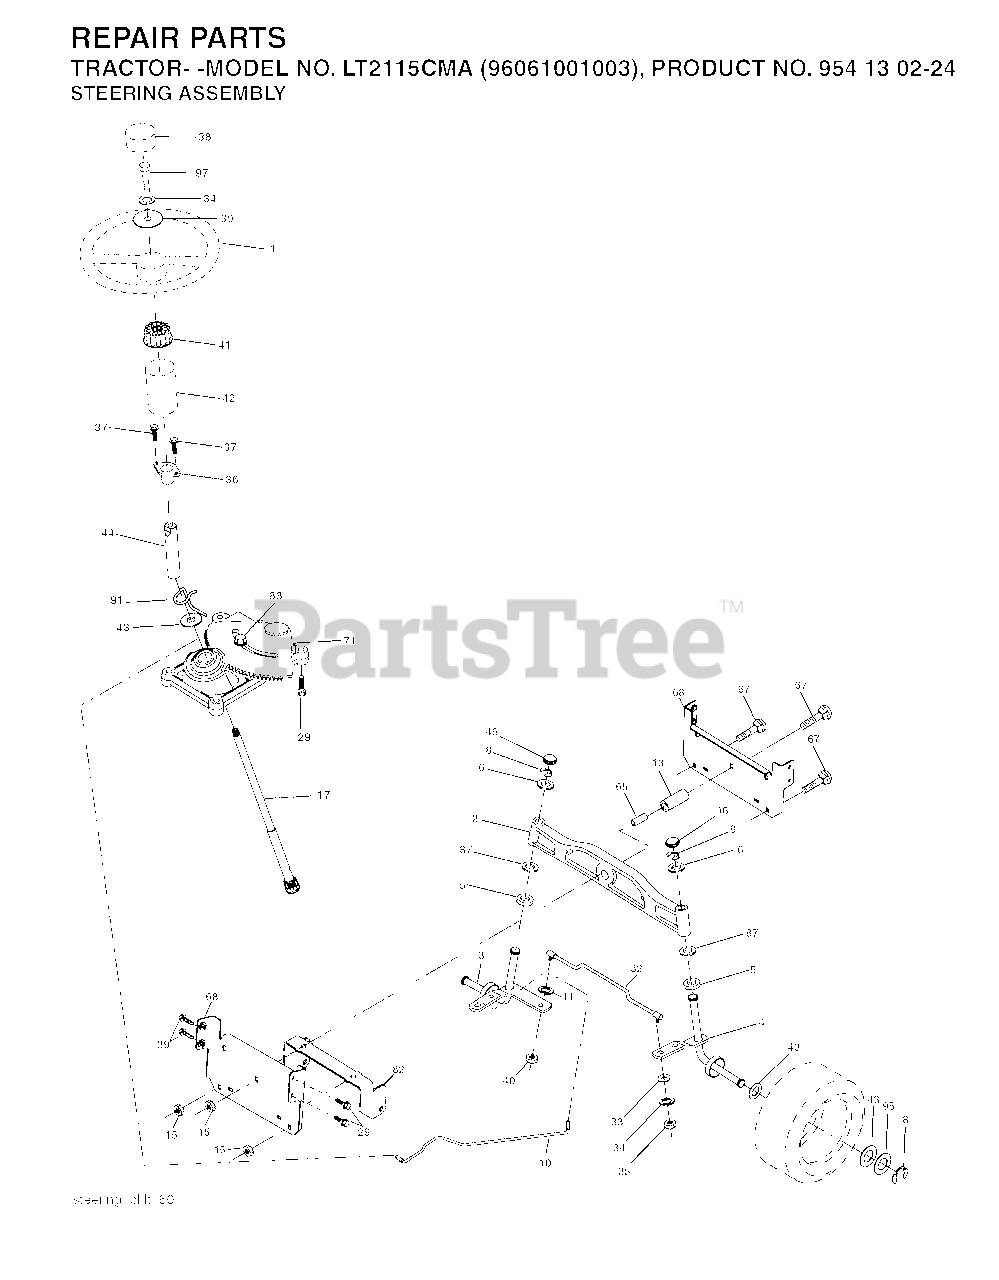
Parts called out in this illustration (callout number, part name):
1	WHEEL.STEERING.PREM.2.BLK
2	AXLE ASSY FRONT
3	SPINDLE.ASM.LH.15"TIRES
4	SPINDLE.ASM.RH.15"TIRES
8	RING CLIP
10	DRAGLINK.15".TIRES.2001
11	WASHER, LOCK 3/8
13	TUBE, PIVOT AXLE
15	NUT
17	SHAFT STEERING SPLINE
29	SCREW, 3/8-16X3/4
32	ROD.ASM.TIE.BALL.JOINT.NOVAN
33	WASHER M
34	LOCKWASHER
35	NUT, CROWNLOCK
36	BUSHING, STEERING
38	INSERT.CAP.STRG.WH.BLACK
39	WASHER.11/32
40	NUT CROWNLOCK 3/8-24
41	ADAPTER, WHEEL STNG..
42	BOOT.STEERING.SHAFT.BLACK
44	SHAFT.EXTEN.STRG.SPLINE
46	CAP.SPINDLE
65	SPACER BRACE AXLE
67	BOLT CARRIAGE
68	BRACE.AXLE.15"TIRES
71	STEERING ASM
82	BRACKET
87	WASHER, FLAT .781 X 1 1/2"
88	BOLT, SHOULDER 7/16-20
91	CLIP.STEERING
95	WASHER.HARDENED
